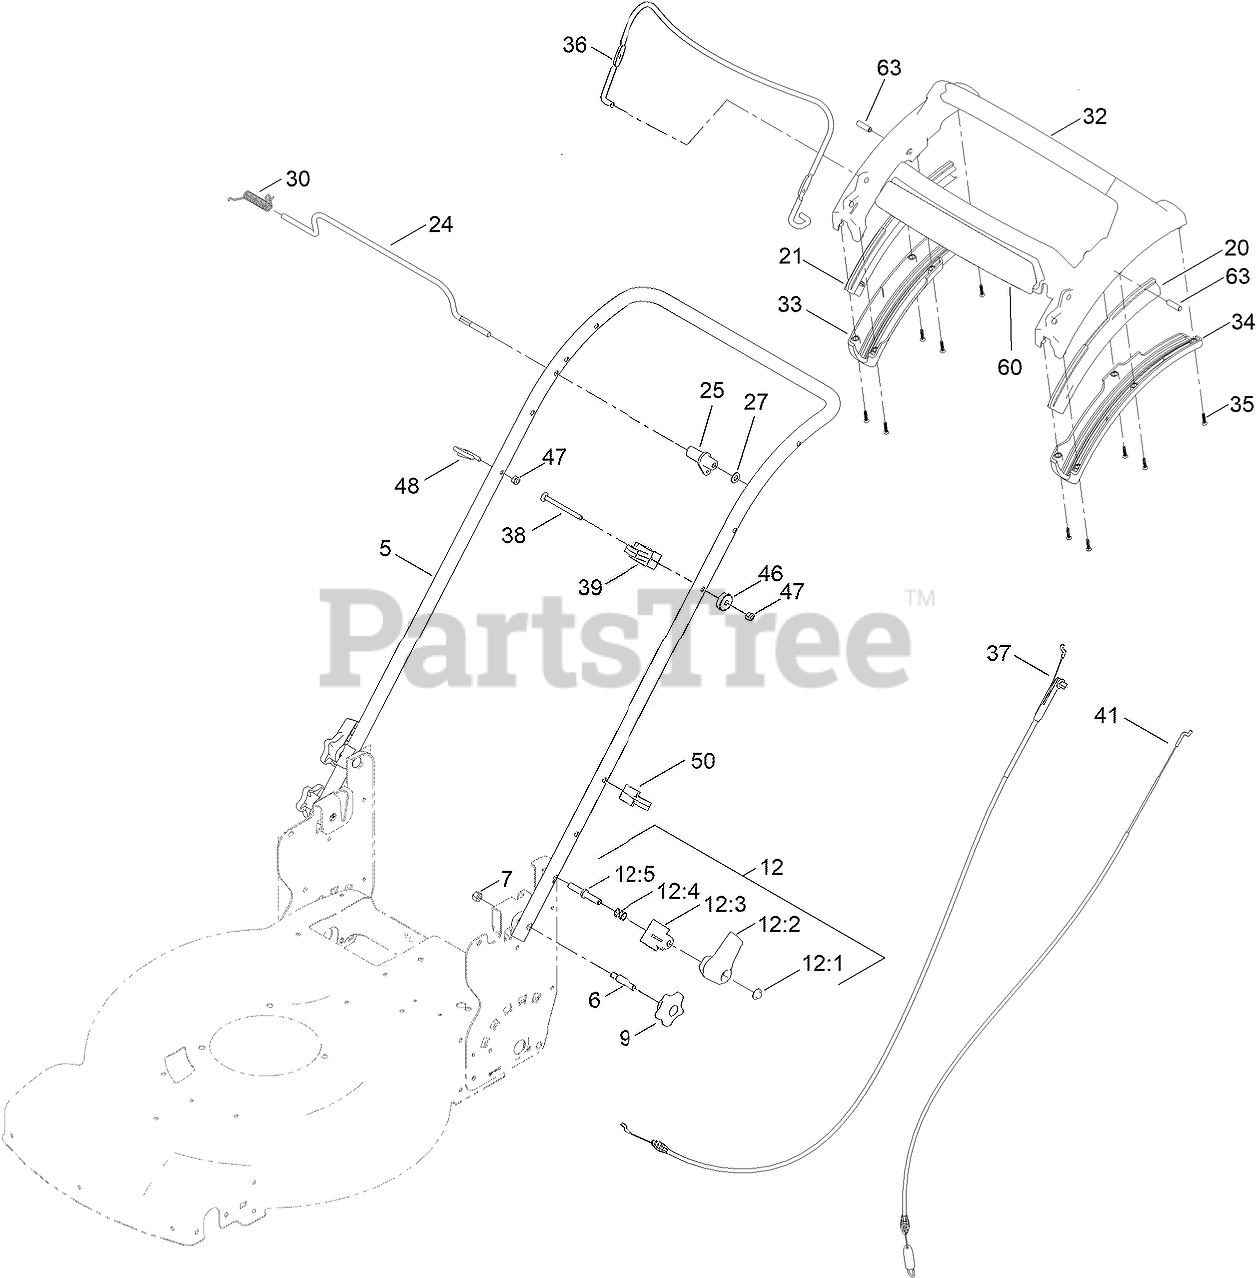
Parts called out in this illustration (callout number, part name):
5	HANDLE-CURVED
6	BOLT-SHOULDER, HANDLE
7	NUT-HEX
9	KNOB-HANDLE
12	QUICK RELEASE ASM
12:1	NUT-PUSH
12:2	LEVER-RELEASE
12:3	ANCHOR-SPRING
12:4	SPRING-COMPRESSION
12:5	ROD-RELEASE
20	GUIDE-CURVED, LH (RWD)
21	GUIDE-CURVED, RH (RWD)
24	ROD-CONTROL, TRACTION
25	LEVER-TRACTION, RWD
27	WASHER-PLAIN
30	SPRING-TORSION
32	HANDLE-PERSONAL PACE, CURVED
33	BOTTOM-HANDLE, RH
34	BOTTOM-HANDLE, LH
35	SCREW-PPH
36	BAIL-BRAKE
37	CABLE-BRAKE, PP BS
38	SCREW-CARR
39	ANCHOR-CABLE, RWD
41	CABLE-TRACTION, RWD (PP)
46	WASHER-CURVED
47	NUT-HEX
48	GUIDE-ROPE
50	GUIDE-CABLE
60	DECAL - ADS, HANDLE
63	PIN-HANDLE, PP
